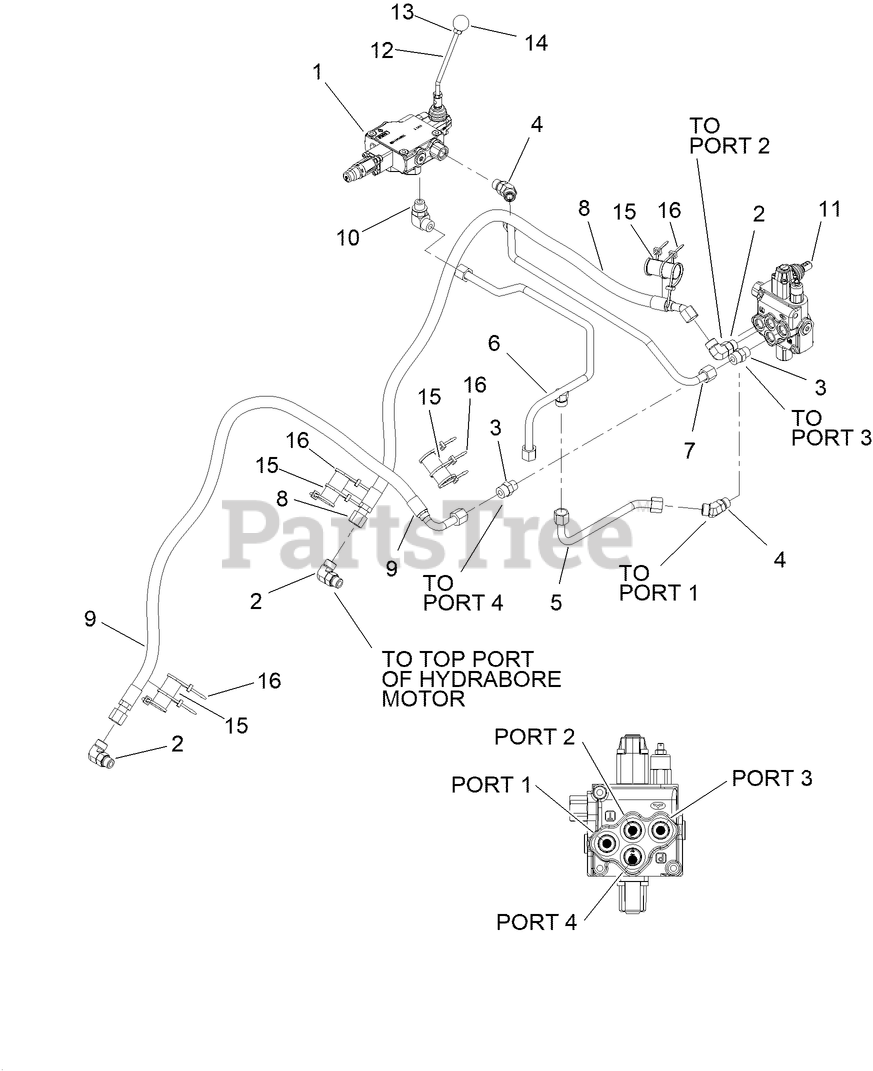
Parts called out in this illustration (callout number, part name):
1	VALVE-TRENCHER
2	CONNECTOR (10S-10O90)
3	CONNECTOR (10S-10O)
4	CONNECTOR (10S-10O45)
5	HARDLINE (-10 HYDRABORER TO RETURN)
6	HARDLINE (-10 TRENCHER TO RETURN)
7	HARDLINE (-10 HYDRABORER TO TRENCHER)
8	HOSE (10OFX45-53"-3000)
9	HOSE (10OFX90L-54"-3000)
10	CONNECTOR (10S-10O90)
11	HYDRO VALVE ASM
12	LEVER-TRENCHER
13	NUT
14	KNOB-ROUND
15	PROTECTOR-HOSE
16	TIE-CABLE
